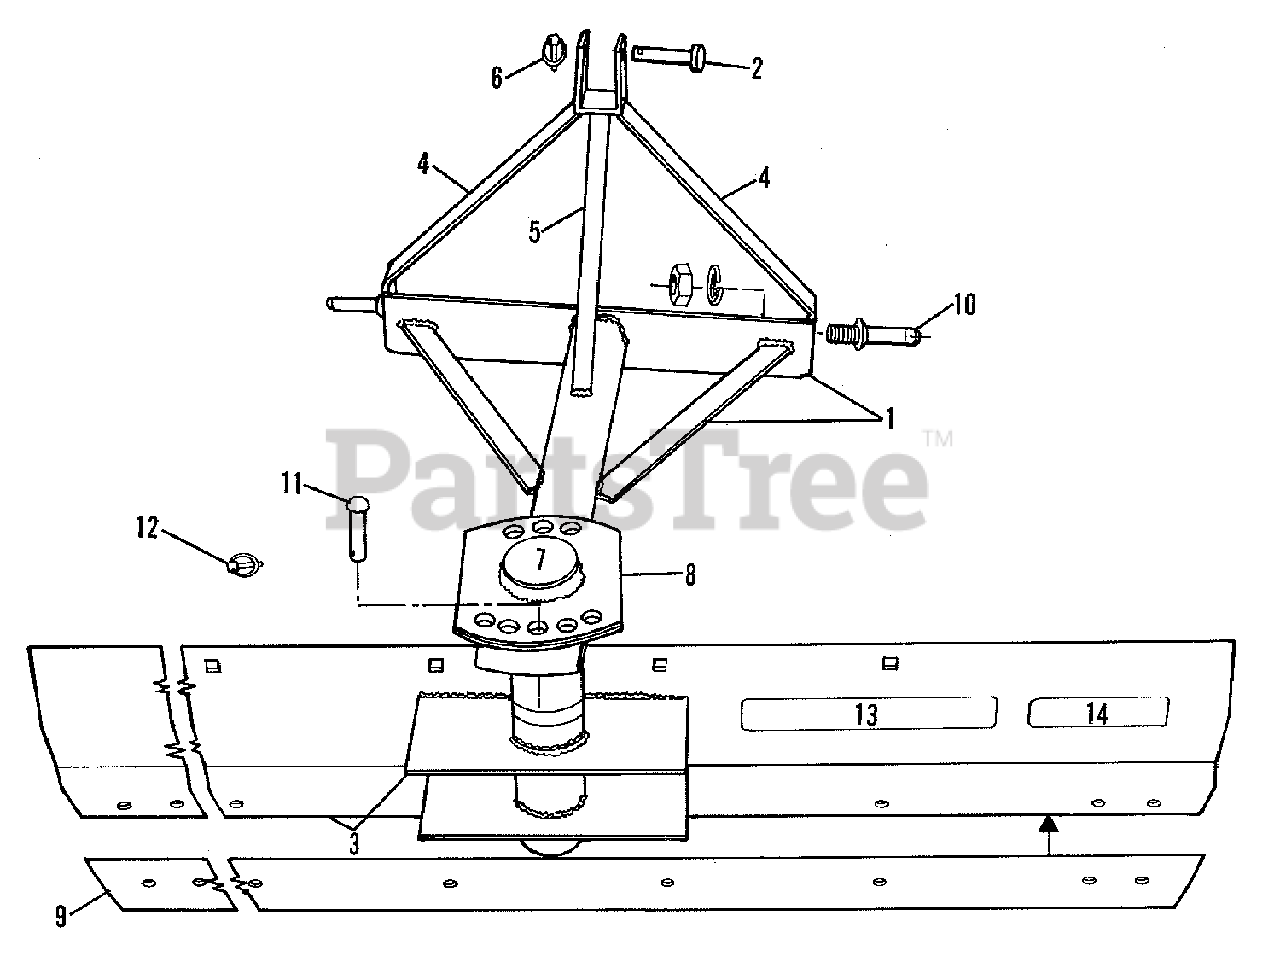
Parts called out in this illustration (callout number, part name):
1	FRAME ASSEMBLY, Main
2	PIN, Hitch, Upper
3	FRAME ASSEMBLY, Moldboard
5	BRACE, Frame
5	CAPSCREW, 5/8NC x 4
5	CAPSCREW, 5/8NC x 2-1/2
5	LOCKWASHER, 5/8
9	BLADE, Cutting
9	BOLT, Plow, No. 3 Head, 5/8NC x 1-3/4
9	LOCKWASHER, 5/8
10	PIN, Link (Cat. 1)
10	LOCKWASHER, 7/8
10	NUT, 7/8 NF
11	PIN, Adjusting
13	DECAL (Allis-Chalmers)
14	DECAL (46 Model Identification)
